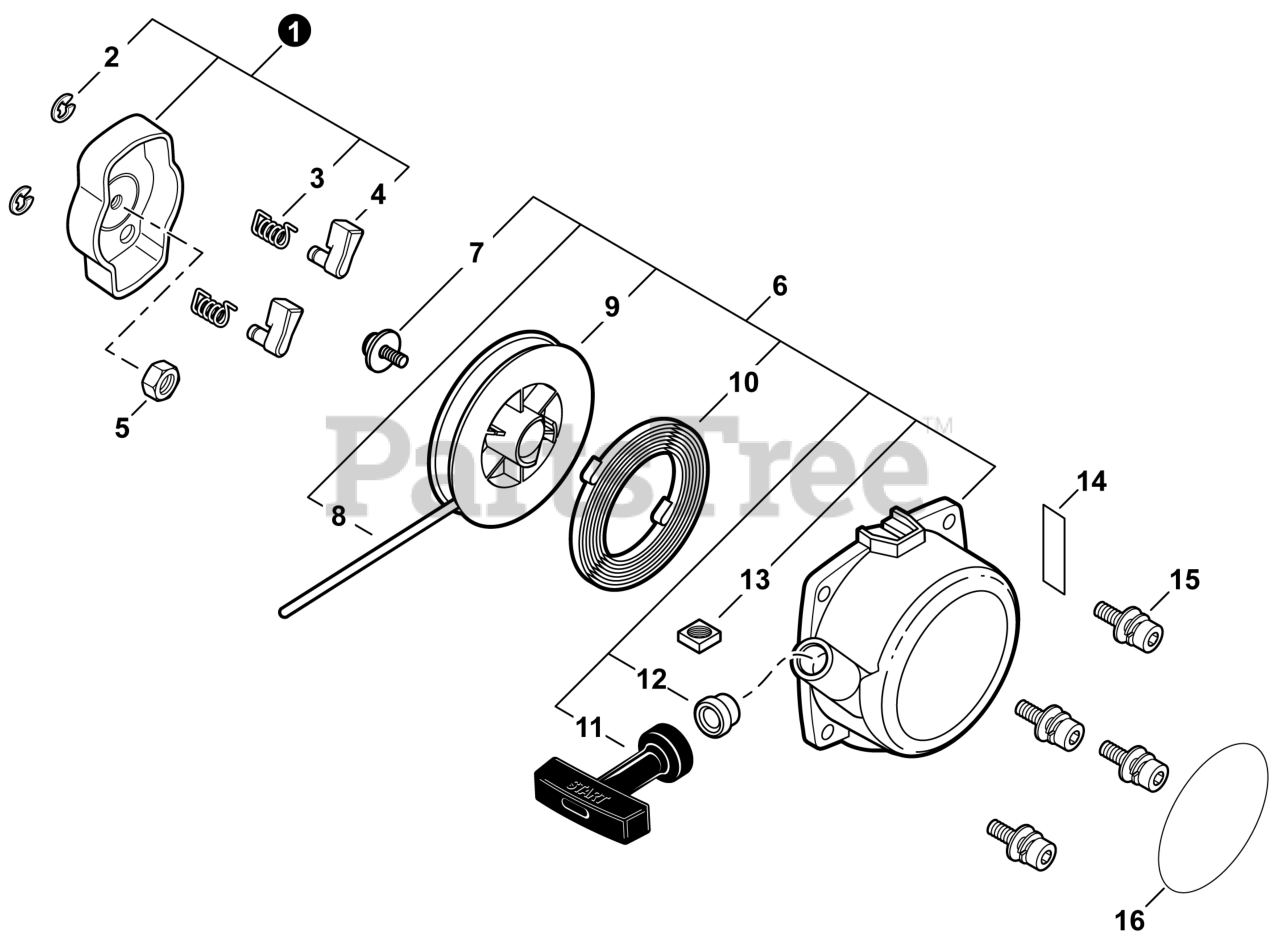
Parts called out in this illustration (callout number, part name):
1	PAWL ASSY, STARTER
2	E-RING 4
3	SPRING, RETURN
4	PAWL, STARTER
5	NUT 8x1.25
6	STARTER ASSY, RECOIL
8	ROPE, STARTER 3.5x850
9	REEL, ROPE
10	SPRING, RECOIL
11	GRIP, STARTER
12	GUIDE, ROPE
13	NUT M5
14	LABEL - CAUTION - HOT
15	SCREW 4x14
16	LABEL - STARTER - SHINDAIWA
